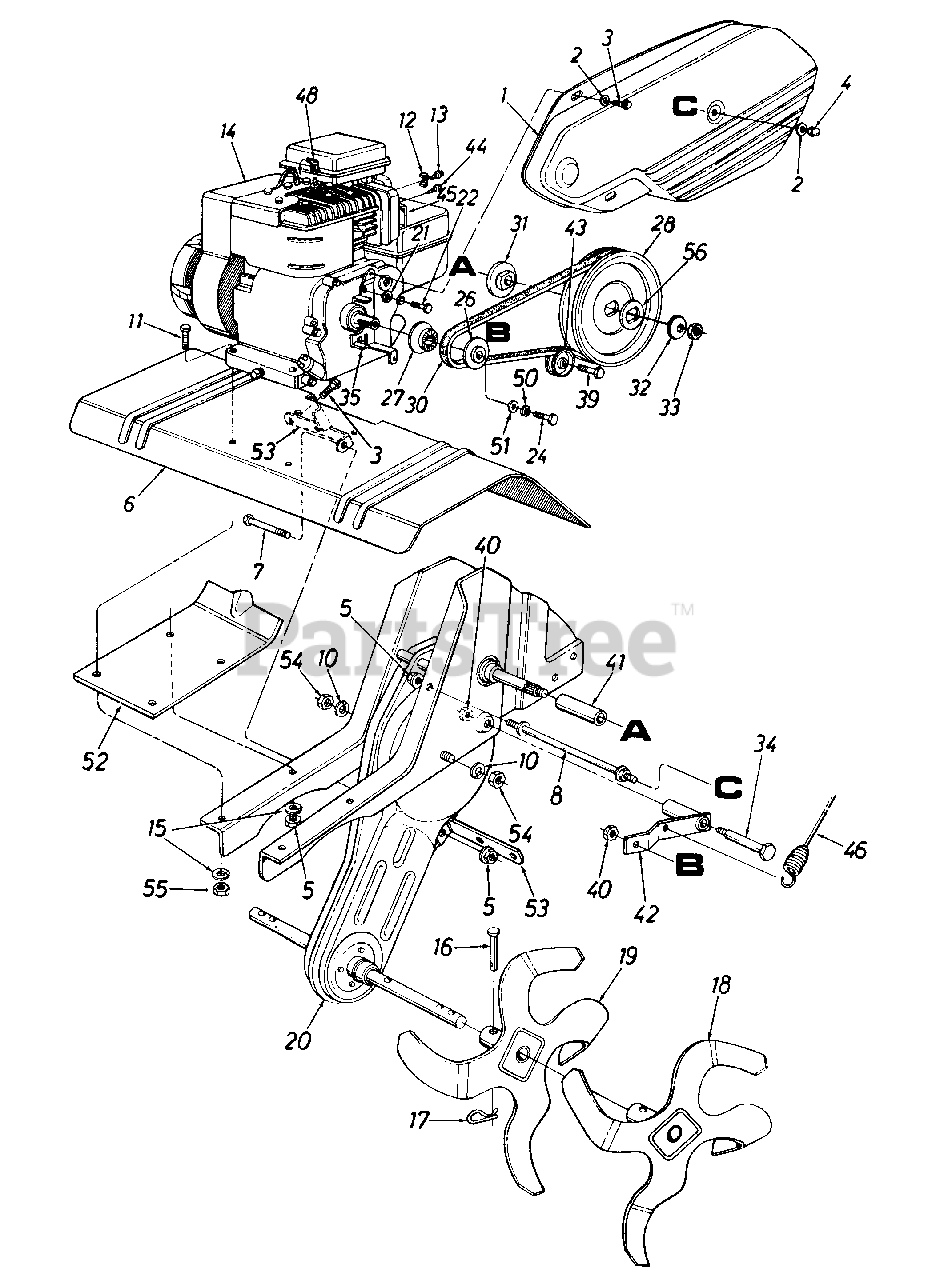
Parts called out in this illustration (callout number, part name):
2	Fl-Wash. .266" I.D. x .625" O.D.
3	Hex Wash. Hd. TT-Tap Scr. 1/4-20 x .5" Lg.
4	Hex L-Stop Nut 1/4-28 Thd.
5	Hex Flange Top L-Nut 5/16-18 Thd. (Gr. 5)
8	Belt Cover Bolt
10	L-Wash. 7/16" I.D.
11	Hex Bolt 5/16-18 x 1.75" Lg.
12	Casing Clamp
13	Hex Sems Scr. #10-32 x .62" Lg.
14	Engine
15	Spec. L-Nut 5/16" I.D.
16	Clevis Pin .375" Dia. x 1.75" Lg.
17	Internal Cotter Pin
20	Chain Case Ass'y. Comp.
21	L-Wash. 5/16" I.D.
22	Hex Bolt 5/16-24 x .5" Lg.
24	Hex Bolt 3/8-24 x 1.25" Lg.
26	Outer Engine Pulley Half
27	Inner Engine Pulley Half
28	Fl-Pulley 6" Dia.
30	"V"-Belt
31	Pulley Mounting Adapter
32	Bell-Wash. .535" I.D. x 1.5" O.D.
33	Hex Jam Nut 1/2-20 Thd. (Gr. 5)
34	Shld. Bolt .498" Dia. x 1.45" Lg.
39	Hex Cap Bolt 3/8-16 x 1.25" Lg.
40	Hex Cent. Jam Nut 3/8-16 Thd.
41	Spacer .64" I.D. x 2.4" Lg.
42	Tine Idler Brkt. Ass'y.
43	Fl-Idler 2" O.D.
44	Hex Self-Tap Scr. #8-32 x .38" Lg.
45	Muffler Deflector
46	Clutch Control Cable
48	Spark Plug Boot
50	L-Wash. 3/8" I.D.
51	Fl-Wash. 3/8" I.D. x 1" O.D.
54	Hex Nut 7/16-20 Thd.
55	Hex Nut 5/16-18 Thd.
56	Bearing Retainer Washer
